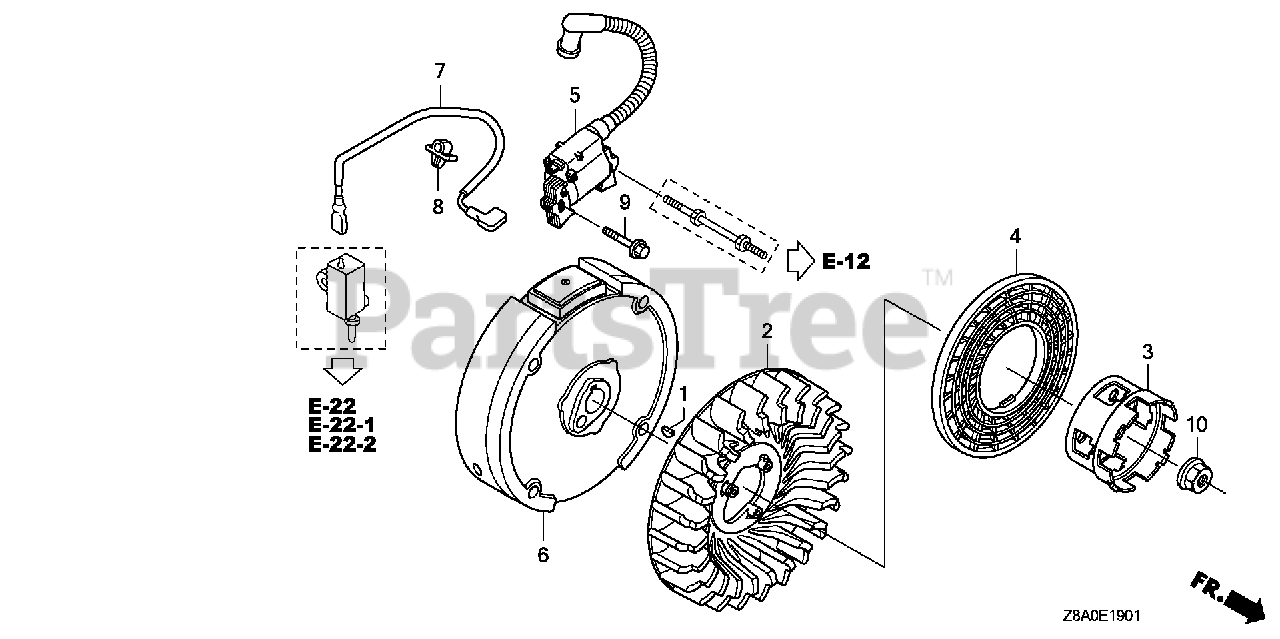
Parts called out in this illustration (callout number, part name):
1	KEY, SPECIAL WOODRUFF (25X18)
2	FAN, COOLING
3	PULLEY, STARTER
5	COIL ASSY., IGNITION (PHELON)
7	WIRE, STOP SWITCH
8	CLIP A, CABLE (3.8MM BLACK) (NIFCO)
9	BOLT, FLANGE (6X23) (CT200)
10	NUT, SPECIAL (14MM)
